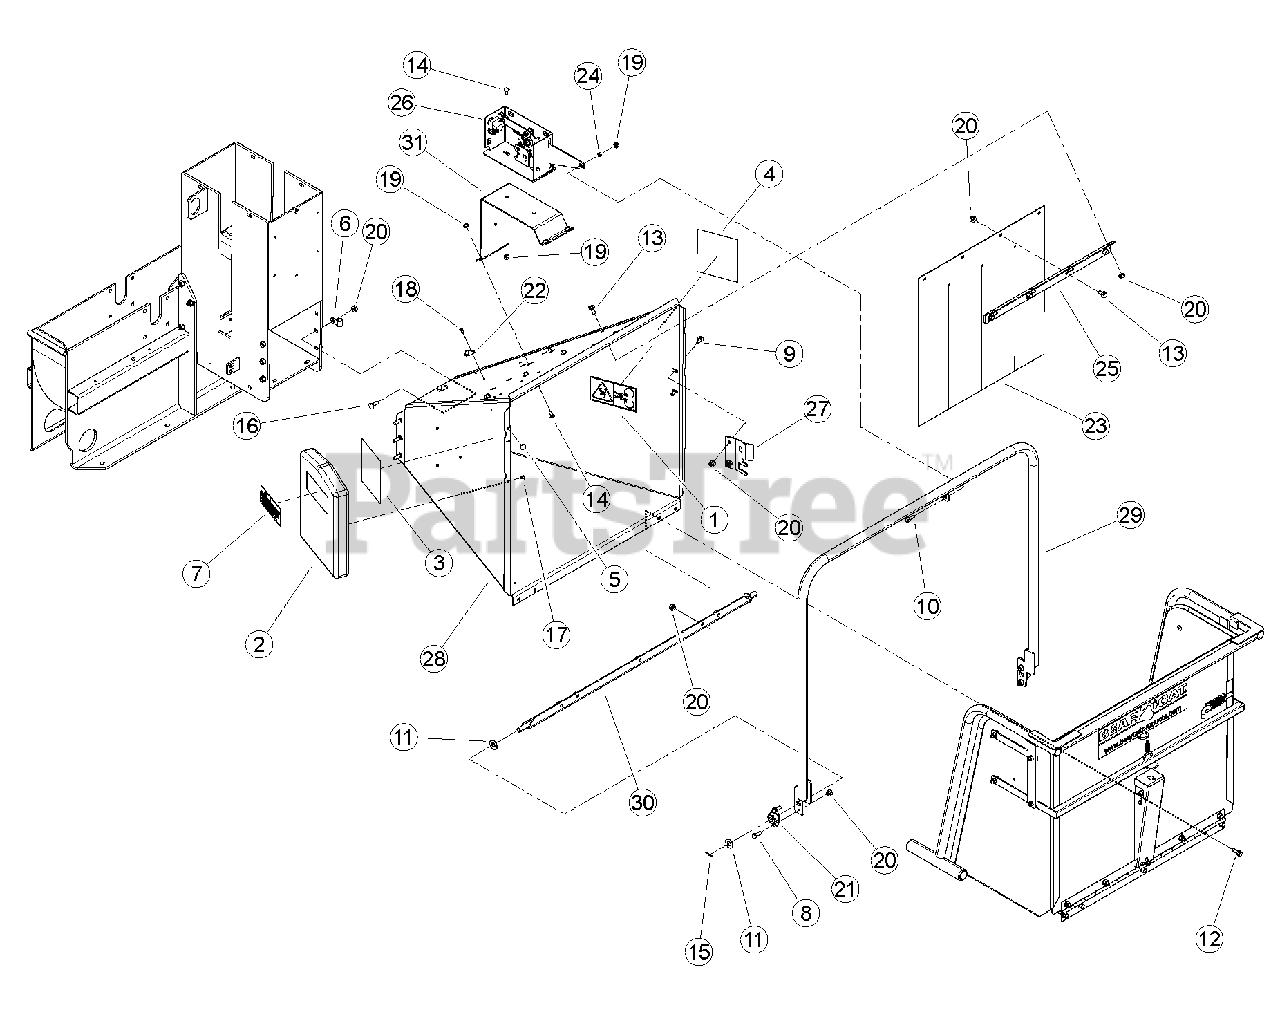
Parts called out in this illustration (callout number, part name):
1	DECAL, BLADE DANGER ISO
2	CONTAINER, INSTR. MANUAL
3	DECAL, FEED POSITION
4	DECAL, FEED POSITION
5	BUMPER, RUBBER
6	CLAMP, 9/16 COATED
7	DECAL, MUTILINGUAL MANUAL
8	BOLT, 3/8 X 1 HEX HD GR5 ZP
9	BOLT, 3/8 X 1" GR5 CRG NC ZP
10	BOLT, 5/16 X 1 FLANGE NC
11	WASHER, 5/8" SAE FLAT ZP
12	BOLT, 3/8 X 1 FLANGE NC
13	BOLT, 3/8 X 3/4 FLANGE NC
14	BOLT, 5/16 X 3/4 GR5 CRG NC ZP
15	PIN, 1/8 X 1.00 ZP COTTER
16	BOLT, 3/8 X 1-1/4" GR5 CRG NC ZP
17	RIVET, AL BLIND 1/4 X 1/2 DOME HEAD
18	RIVET, AL BLIND 1/4 X 3/4 DOME HEAD
19	NUT, 5/16-18 NYLOCK-FLANGE
20	NUT, 3/8-16 NYLOCK FLANGE
21	BEARING, SIDE FLANGE MOUNT 5/8"
22	CLAMP, CABLE MOUNT
23	FLAP, 9 INCH CHUTE
24	SPACER, IDLER PIVOT
25	SUPPORT, 9 INCH CHIPPER FLAP
26	ASSEMBLY, "CE" SWITCH BOX
27	PLATE, TRAY STOP
28	WELDMENT, BIG CHIPPER CHUTE
29	WELDMENT, CONTROL ARM
30	WELDMENT, CONTROL PIVOT
31	MOUNT, SWITCH BOX
